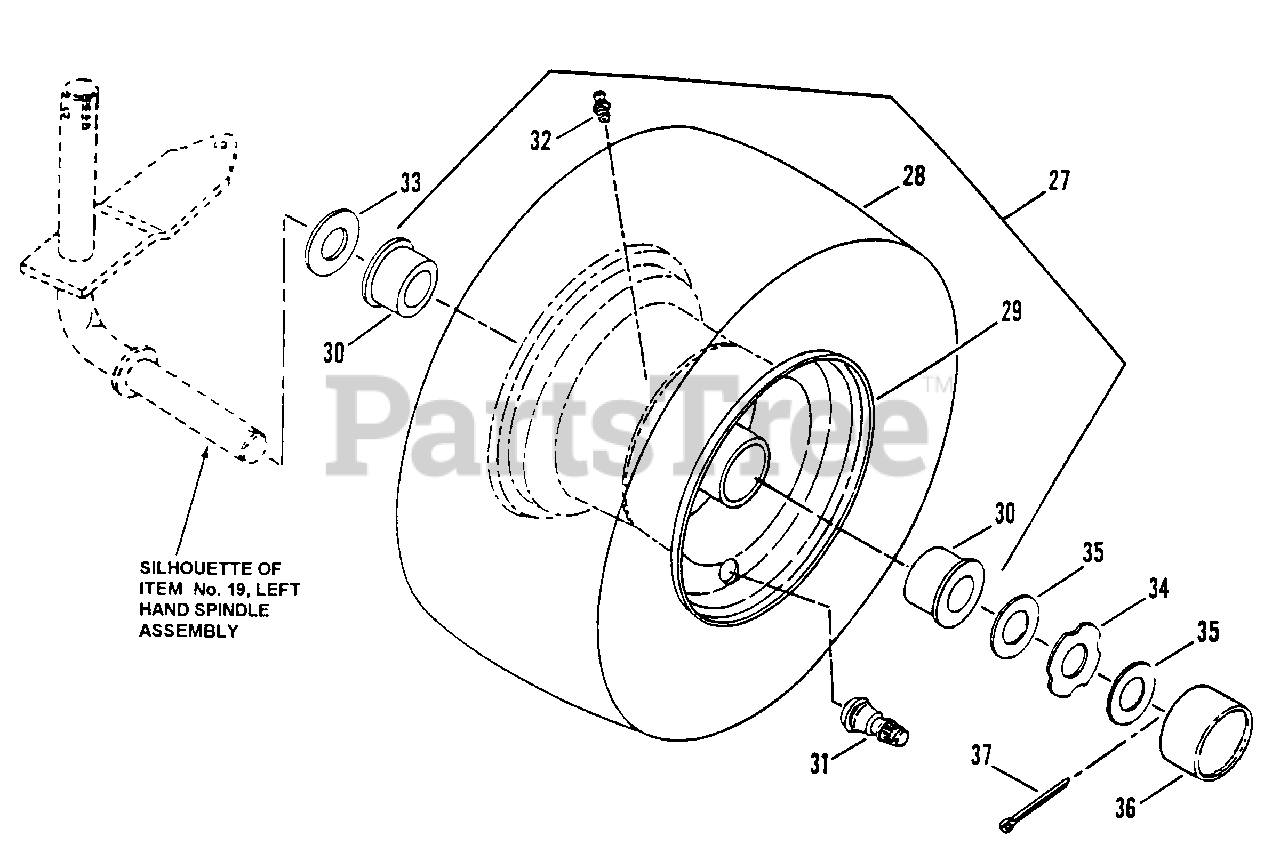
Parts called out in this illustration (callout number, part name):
27	ASSEMBLY, Front Tire & Rim
28	TIRE, 15 x 6.00
29	RIM, 5.50 x 4.00
30	BEARING, Wheel
31	VALVE, Air (Snap-In)
32	FITTING, Lube 1/4-28 Tapered Thread
33	WASHER, Flat, .15x.78 I.D. x 1.5" O.D.
34	WASHER, Hub-Cap Retaining
35	WASHER, Flat, .07 x .77 I.D. x 1.31" O.D.
36	HUB-CAP
37	COTTER-PIN, 5/32 x 1"
